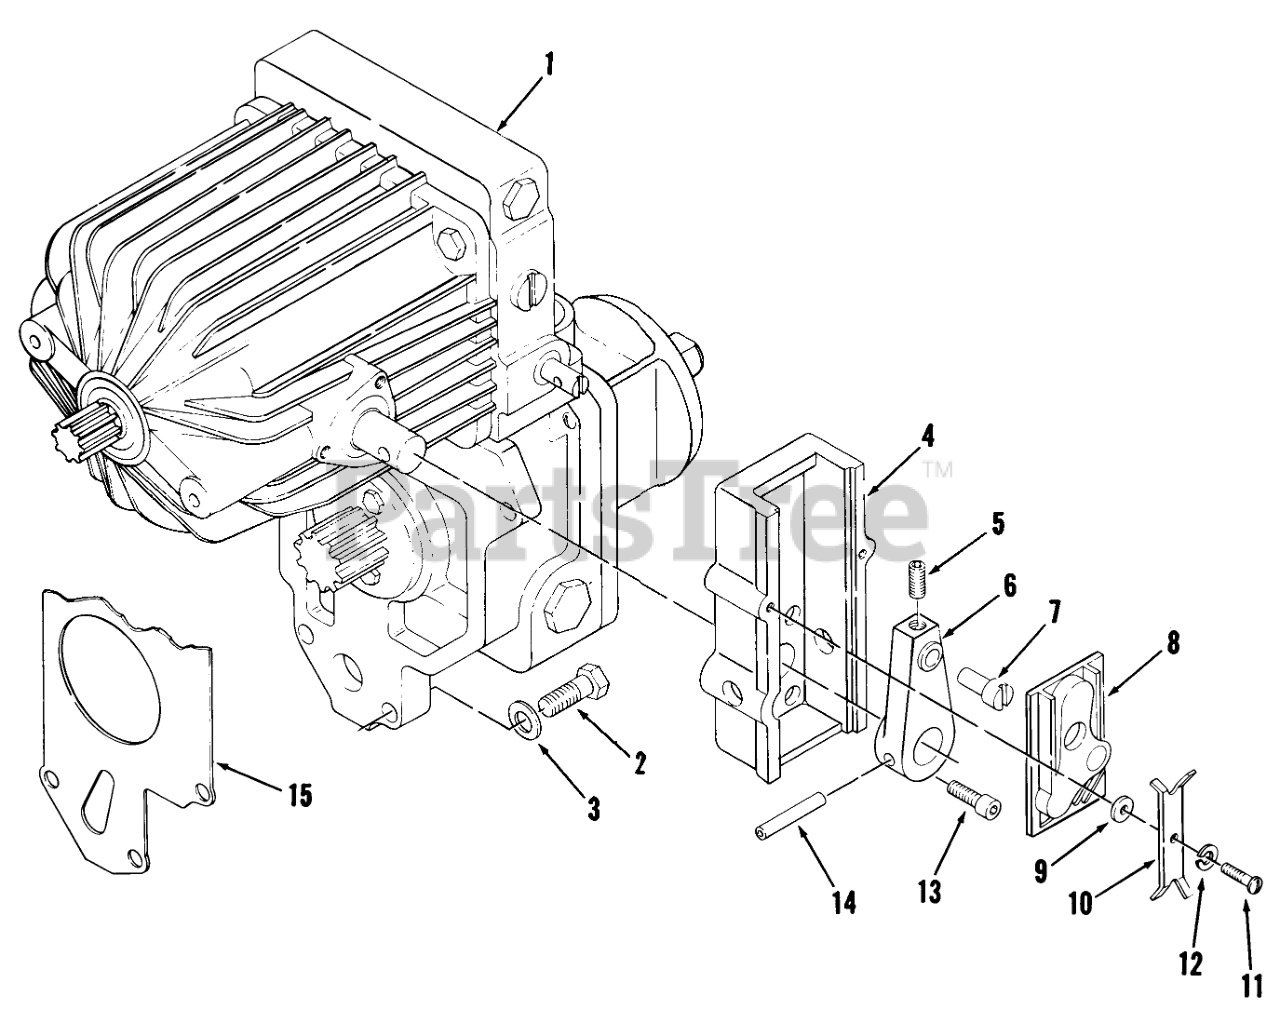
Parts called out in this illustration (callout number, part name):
1	Pump & Motor C-121 Only
1	Trans Assembly Piston To Piston-Complete
2	BOLT
3	Washer
4	SUPPORT CAM BLOCK
6	Belt Guide
7	ECC CAM FOLLOWER
8	CAM
9	WASHER
10	TENSION PLATE
11	SCREW
12	LOCKWASHER
13	SHCS 1/4-20 X 1/2
14	PIN-ROLL 1/4 X 1 1/4
15	GASKET
